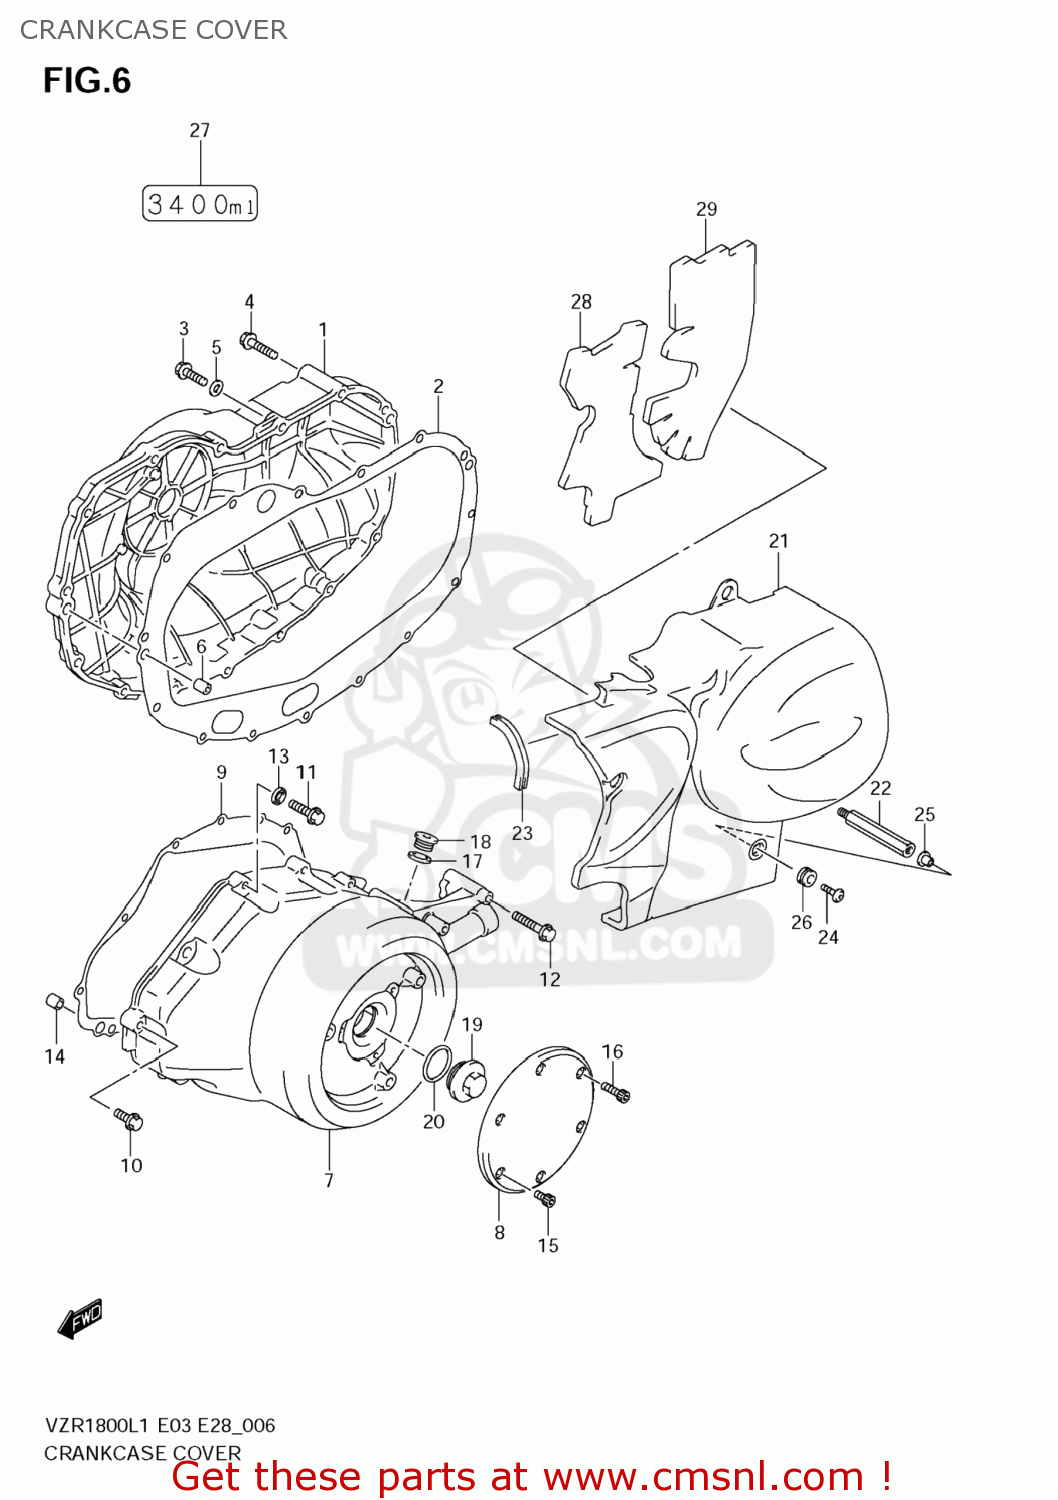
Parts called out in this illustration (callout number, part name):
1	COVER,CLUTCH
2	GASKET,CL COVER (NAS)
3	BOLT(6X30)
4	BOLT(6X60)
5	GASKET(5.8X13X1.2) (NAS)
6	PIN
7	COVER,MAGNETO
8	CAP,MAGNETO COVER
9	GASKET,MAGNETO COVER (NAS)
10	BOLT(6X30)
11	BOLT(6X50)
12	BOLT(6X70)
13	GASKET(5.8X13X1.2) (NAS)
14	PIN
15	BOLT(6X10)
16	BOLT(6X20)
17	GASKET(16X22X2) (NAS)
18	PLUG,16X8
19	CAP
20	O RING(D:3.1,ID:26.4)
21	COVER,SECONDARY DRIVE UNIT
22	BOLT,SEC DRIVE UNIT COVER
23	SCREW(6X20)
24	WASHER
25	CUSHION
26	NOTE,ENGINE OIL
27	DAMPER,MAGNETO COVER CAP
28	DAMPER,SEC DRIVE UNIT COVER
29	DAMPER,SEC DRIVE UNIT COVER
